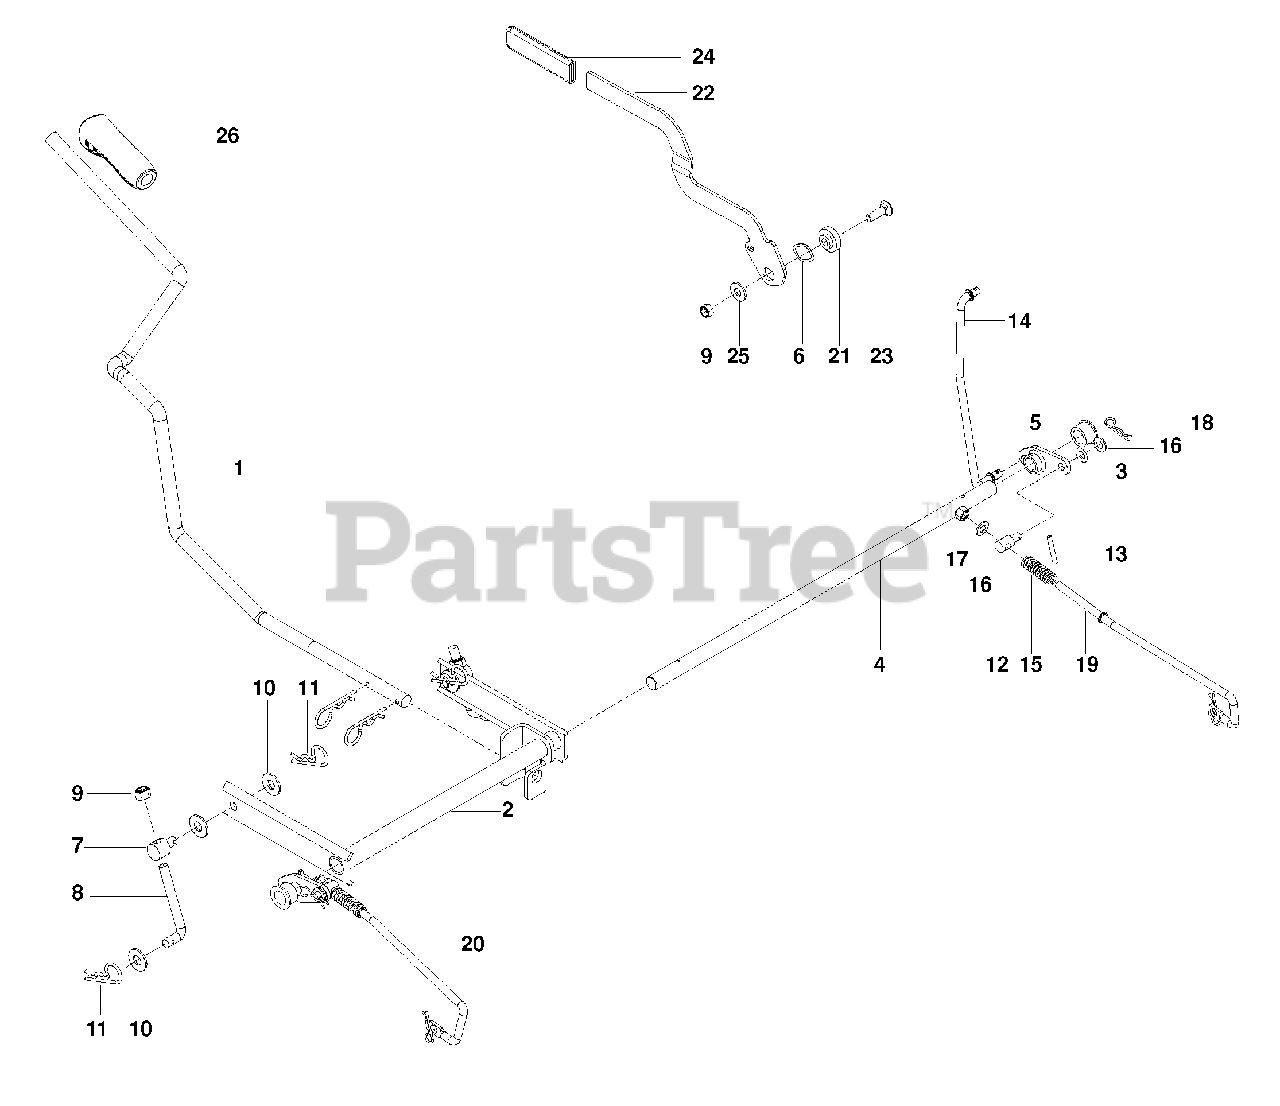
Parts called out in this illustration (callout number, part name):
1	HANDLE, LIFT BLK
2	SHAFT, LIFT BLK
3	BELLCRANK, BRAKE
4	ROD, BRAKE
5	BUSHING, PLASTIC
6	WASHER, .825 WAVE
8	L-ROD 3 1/2"
9	NUT 3/8-16 HEX NYLOC
10	WASHER 3/8 FLAT STD
12	SWIVEL, BRAKE
13	PIN 3/16 x 1 1/4 ROLL
14	LINKAGE, UPPER
16	WASHER 5/16 SAE FLAT
17	NUT 5/16-18 HEX NYLOC
18	HAIRPIN COTTER
19	LINKAGE, BRAKE RT
20	LINKAGE, BRAKE LT
21	PIVOT, BRAKE ARM
22	HANDLE, BRAKE
23	RHSNB 3/8-16 x 1 1/4
24	GRIP, BRAKE HANDLE
25	WASHER 7/16 SPRING DISK
26	GRIP, LIFT HANDLE
